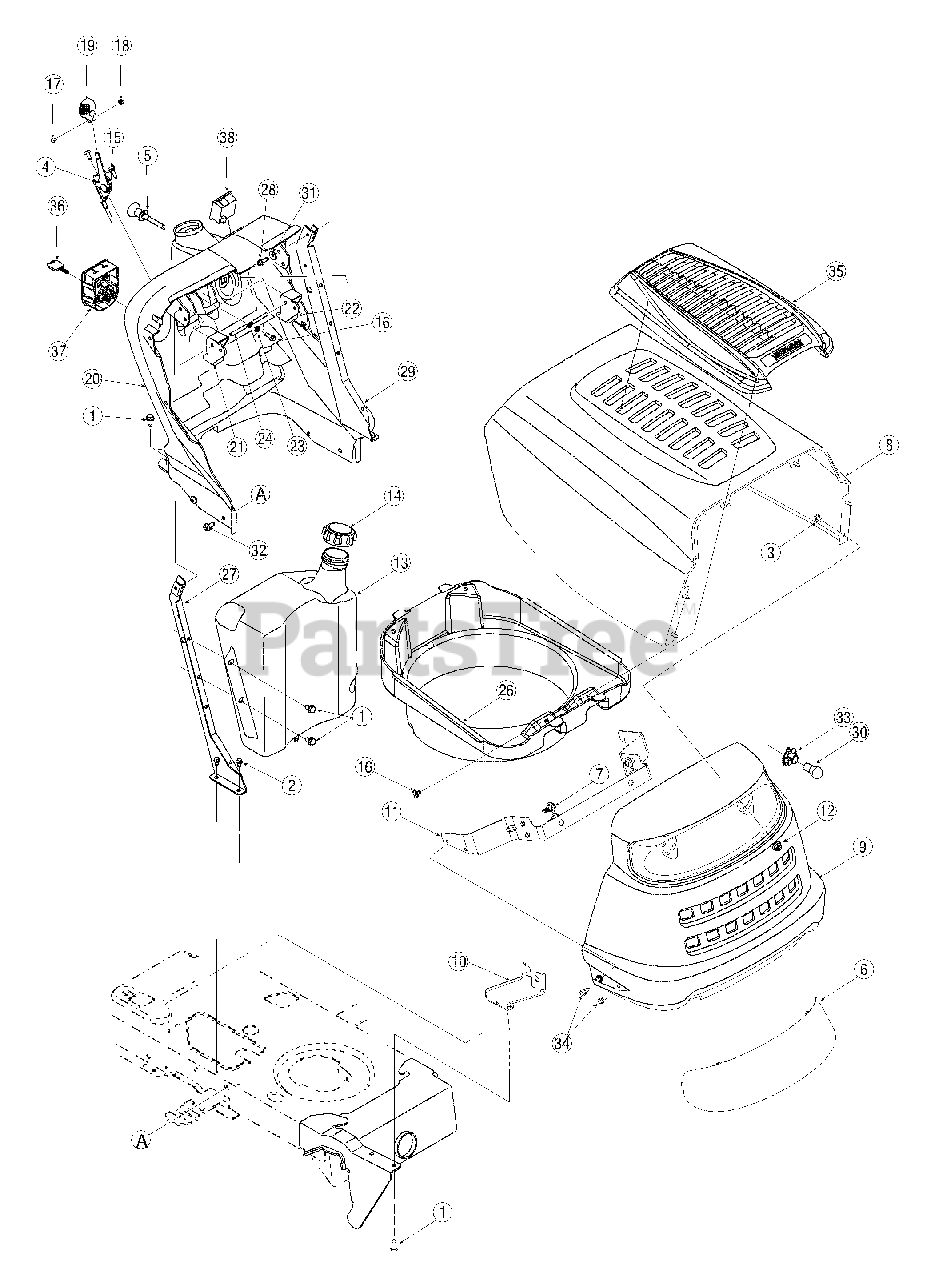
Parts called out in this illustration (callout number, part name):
1	Screw, 5/16-12 x.750
2	Self-tapping Screw, 1/4-20 x.5
3	Hex Cap Screw, 1/4-20 x.62
4	Throttle Control/Cable
5	Choke Knob/Cable
6	Headlight Lens
7	Shoulder Screw,.43 x.29
13	Fuel Tank, Three Gallon
14	Fuel Cap
15	Screw, 1/4-14 x.625
16	Self-tapping Screw, 1/4-15 x.75
17	Truss Phillips Screw, #8-32 x.375
18	Hex Nut, #8-32
19	Throttle Control Knob
20	Dash Panel
21	Cruise Control Button
22	Parking Brake Button
23	Flat Washer, 9/32 x 1/2 x 1/16
24	Brake/Cruise Pivot Rod
26	Hood Plenum
30	Lamp
31	Bell Washer,.265 x.75 x.062
32	Screw, 5/16-18 x.75
33	Headlight Socket
34	Hex Index Screw, 1/4-20 x.625
35	Hood Cover, 5 Style
36	Ignition Key w/ plastic cover
37	Ignition Switch
38	Systems Ind. Monitor w/ Ammeter
